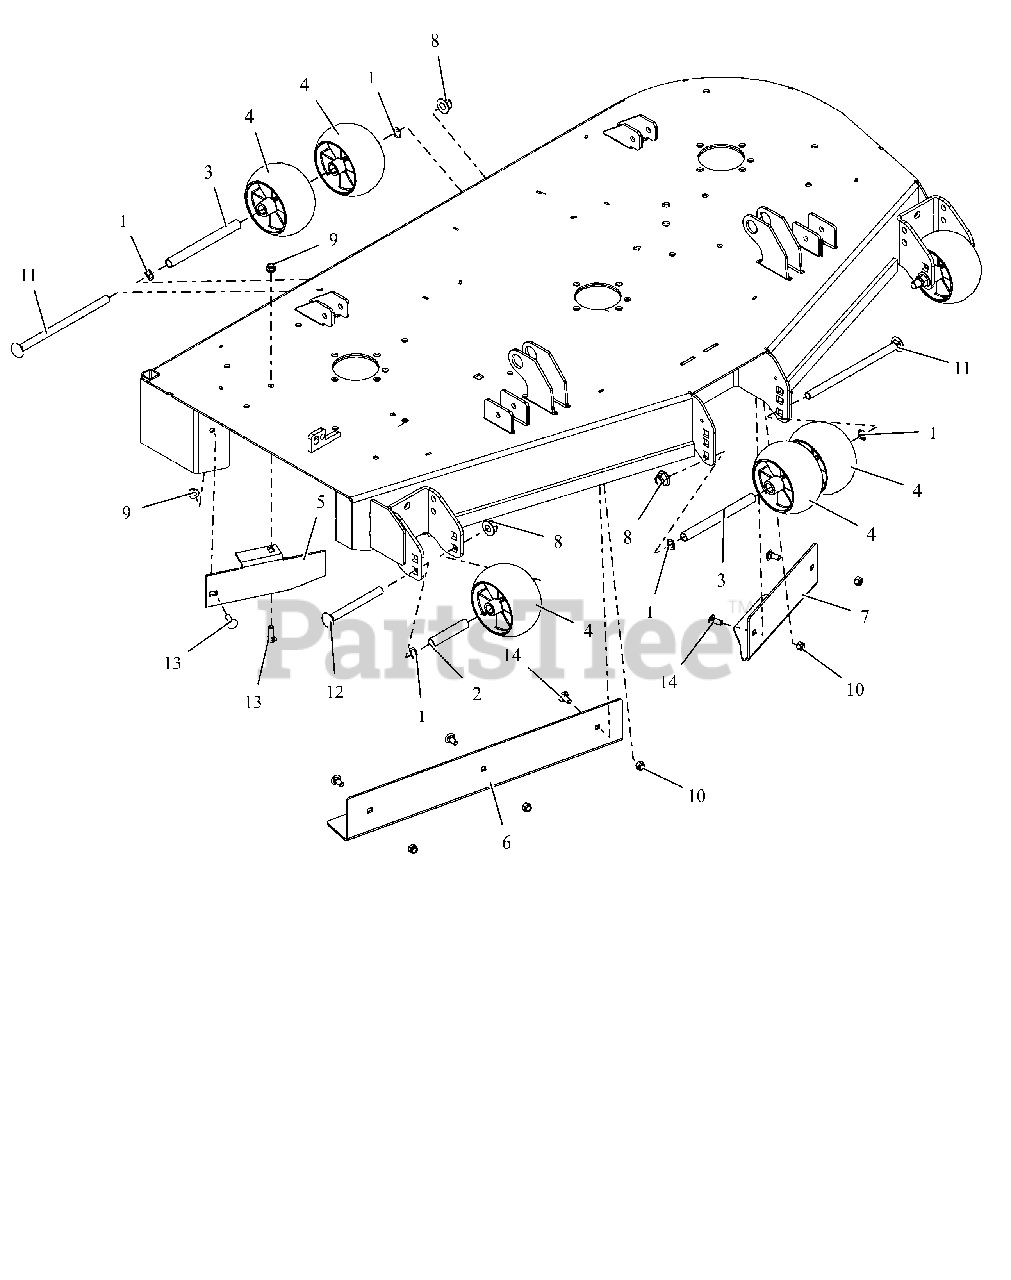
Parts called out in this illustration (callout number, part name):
1	WAVE WASHER .531X.781X.125FH
2	SPACER, .510X.625X3.35
3	SPACER, .510X.625X6.50
4	ANTI-SCALP WHEEL - 5X3 CTR
5	BAFFLE, DISCHARGE, 52"
6	BAFFLE, 52" RH VACUUM (RED)
7	BAFFLE, 52" LH VACUUM (RED)
8	NUT,NYL-FLG .50-13 GF ZCC
9	NUT,NYL-FLG .31-18 GF ZCC
10	NUT,NYL .31-18 G5 ZCC
11	BLT, RHSN .50-13X8.50 G5 ZCC
12	BLT, RHSN .50-13X5.00 G5 ZCC
13	BLT,RHSN .31-18X1.00 G5 ZCC
14	BLT,RHSN .31-18X.75 G5 ZCC
